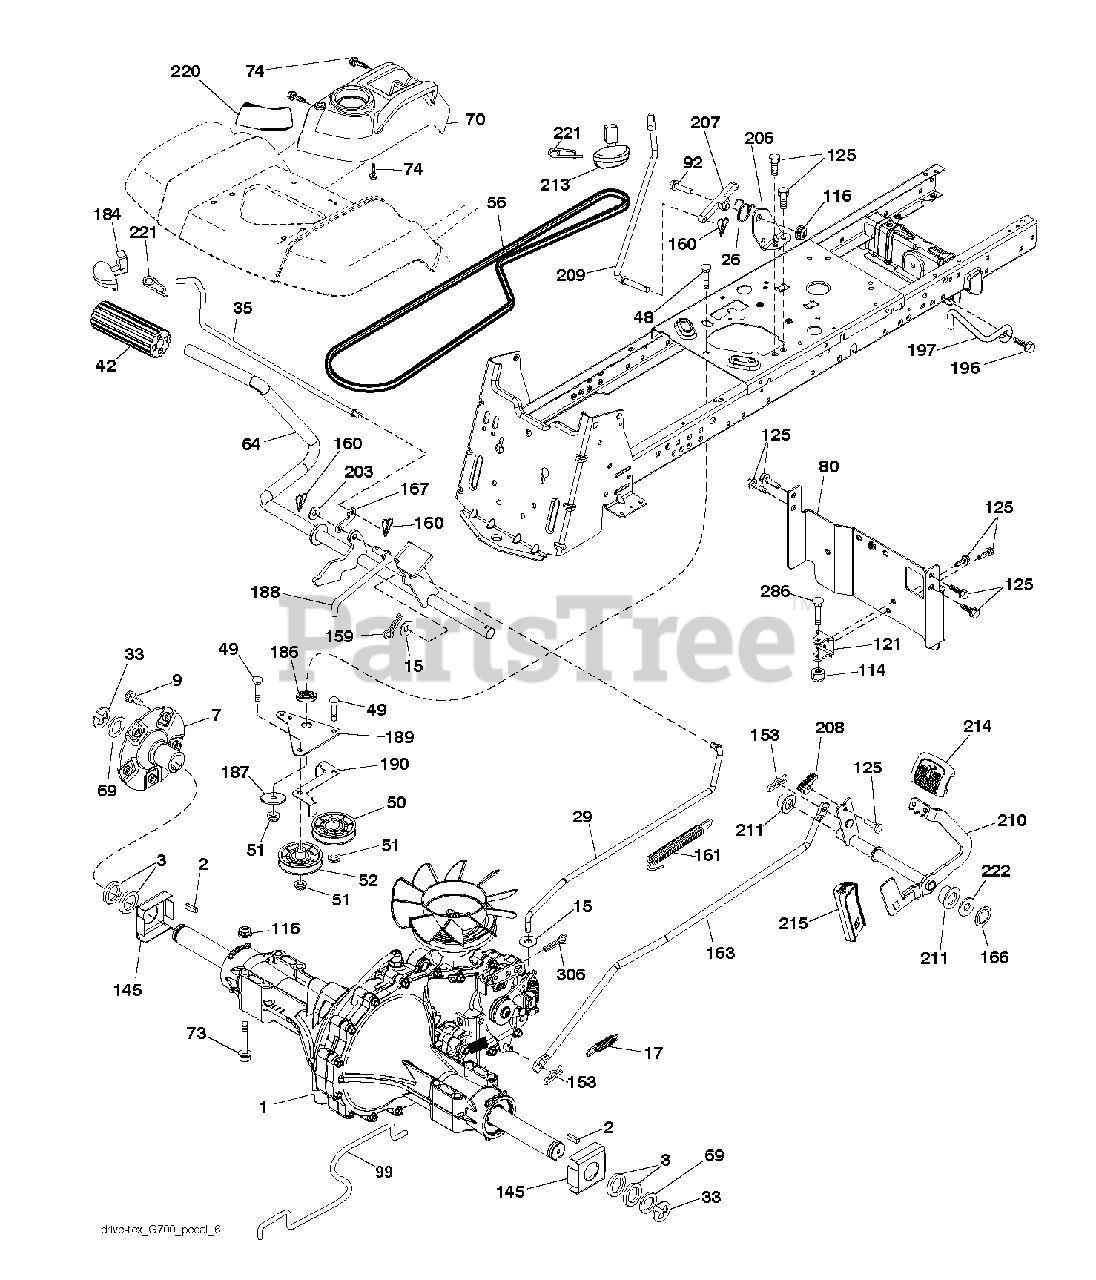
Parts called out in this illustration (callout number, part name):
1	Husqvarna TBD
2	KEY 1/4 X 2.5
7	HUB.ASM.WHEEL.REAR.23"TEX
9	HUB BOLT
15	WASHER
17	SPRING.BRAKE.HG3000/3500
26	SPRING.RETURN.CRUISE
33	E RING HYT
35	ROD.BRAKE.PARTK.HUSQ.TEX
42	PEDAL COVER T
48	BOLT.3/8-16X1.50
50	IDLER.FLAT.910.OFFSET
51	NUT LOCK FLG 3/8-16 UNC
52	IDLER.V-GROOVE.910.OFFSET
56	V-BELT.GROUND.DRIVE.
64	SHAFT.ASM.PEDAL.BRK.CNTR
70	CONSOLE.ASM.RH.GT.FC.HUSQ
73	BOLT HEX FLGHD 5/16-18X3 GR. 5
74	SCREW.HI-LO.CONSOLE
80	STRAP.TORQUE.YT.G700
92	BOLT
99	SPRING.BYPASS.YT.G700
114	NUT.71038.31-18.HEX.NYLOCK
116	NUT LOCK HEX FLANGE 5/16-18
121	BRACKET STRAP TORQUE
125	SCREW
145	WASHER.AXLE.FLANGE.HG-3000
153	RETAINER M
159	COTTER PIN
160	RETAINER CLIP
161	SPRING, RETURN LT
163	ROD PEDAL CONTROL
166	NUT.PUSH.625
167	LATCH.BRAKE.SPRING
184	HANDLE.PARKG.BRK.HUSQ X667
186	SPACER.RETAINER
187	WASHER 12/32X2X10GA
188	RP LINK.CLUTCH.GROUND.DRIVE
189	BELLCRANK.GROUND.DRIVE.TRAPPED
190	KEEPER BELLCRANK ROUND DRIVE
196	SCREW 3/8-16X1
197	BRKT.ANIT-ROTATION.CLUTCH
203	WASHER
206	BRKT.MOUNT.LATCH.CRUIS
207	LATCH.CONTROL.CRUISE
208	GEAR.SECTOR.CONTROL.CR
209	ROD.CONTROL.CRUISE.GT.
210	ROCKER.ASM.PEDAL.CONTR
211	BEARING.NYLON
213	KNOB.CONTROL.CRUSIE.HU
214	PEDAL.FORWARD.HUSQVARNA.DEALER
215	PEDAL.REVERSE.TEX.GT.4
220	REFLECTOR.RH.TEX GT
221	RETAINER.SPRING.CLIP.H
222	WASHER 21/32 X 1-1/4 X 10 GA.
286	BOLT.5/16-18X2.5
306	PIN COTTER
